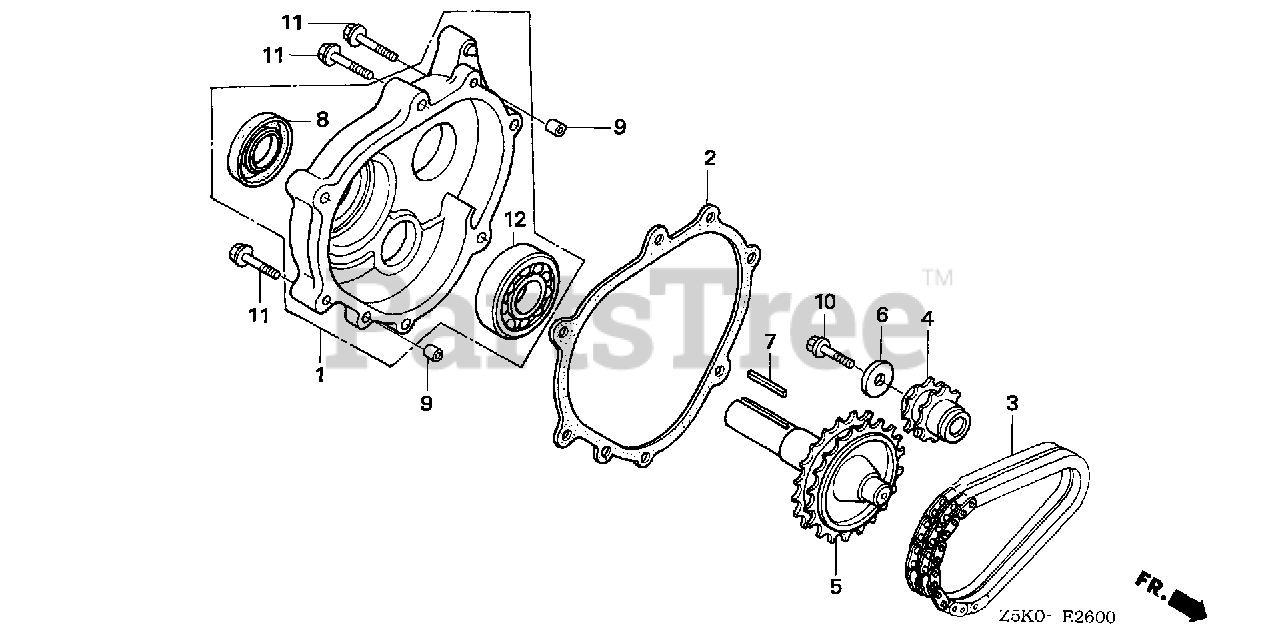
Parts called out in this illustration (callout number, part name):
1	COVER ASSY., CHAIN CASE
2	GASKET, CHAIN CASE COVER
3	CHAIN, P.T.O. DRIVE
4	SPROCKET, DRIVE (14T)
5	SHAFT, P.T.O. (28T)
6	WASHER (8MM)
7	KEY (7X7X33) (OVER SIZE) (YELLOW)
8	OIL SEAL (30X46X8)
9	PIN, DOWEL (8X14)
10	BOLT, FLANGE (8X25)
11	BOLT, FLANGE (8X40)
12	BEARING, RADIAL BALL (6206)
